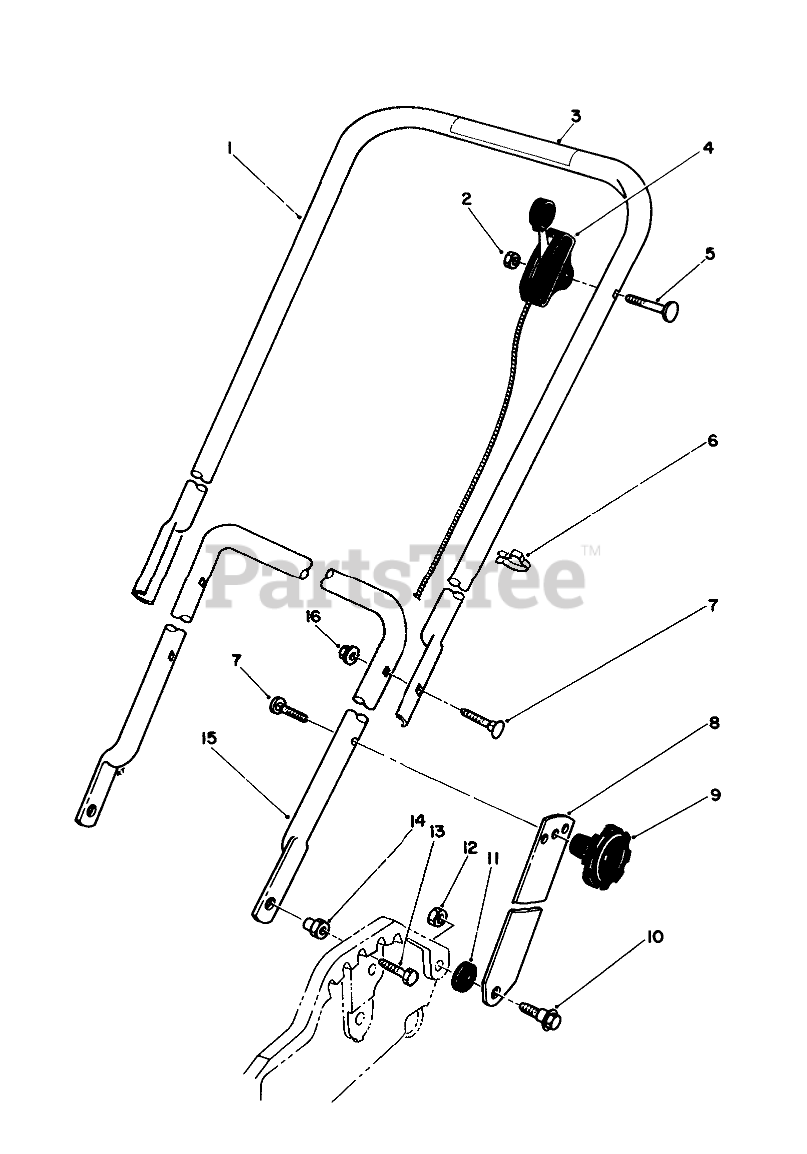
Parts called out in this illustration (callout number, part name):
1	Handle-Upper (Incl. Ref. #3)
2	NUT-LOCK, NI
3	Decal-Danger
4	THROTTLE CONTROL
5	SCREW-HANDLE
6	BOWDEN CLIP
7	SCREW
8	Handle Latch
10	SCREW-SHOULDER
11	SPACER
12	NUT-LOCK, NI
13	SCREW-HH
14	HANDLE PIVOT NUT
15	LOWER HANDLE
16	NUT-LOCK, NI
